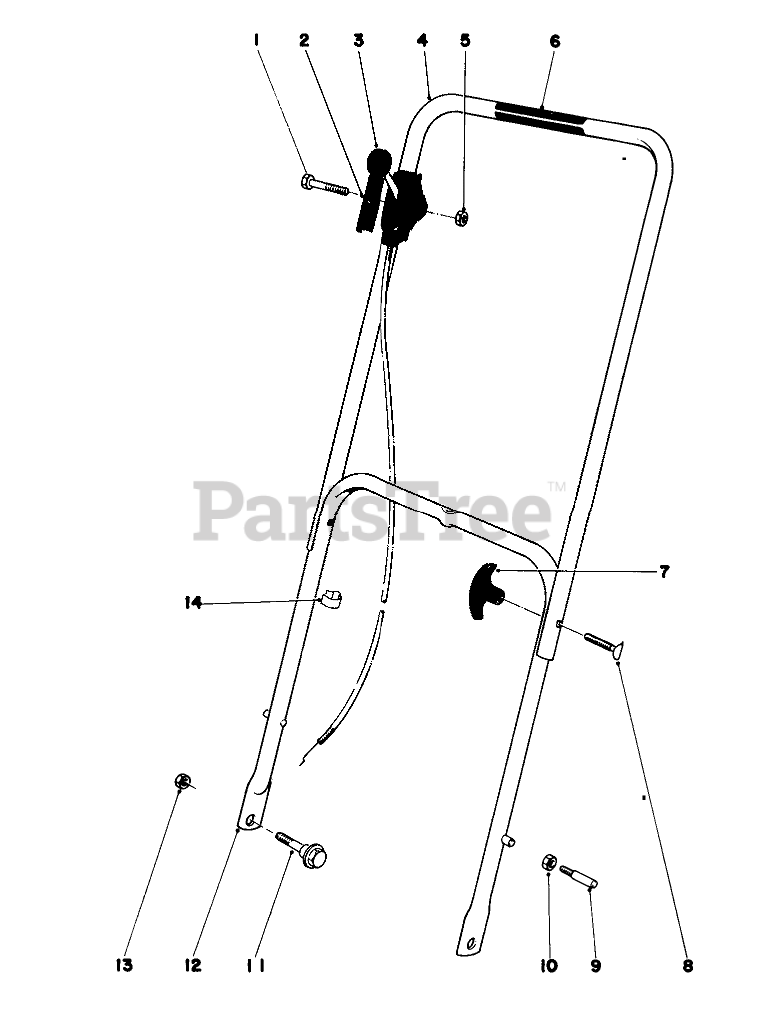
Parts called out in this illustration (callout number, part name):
1	SCREW-HH
2	Decal-Throttle
3	Throttle Control
4	271 Upper Handle
5	NUT-LOCK
6	Decal-Danger (German)
7	Handle Knob
8	HANDLE SCREW
9	HANDLE PIN
10	Nut
11	SCREW-SHOULDER
12	19 LOWER HANDLE ASM
13	Nut
14	BOWDEN CLIP
